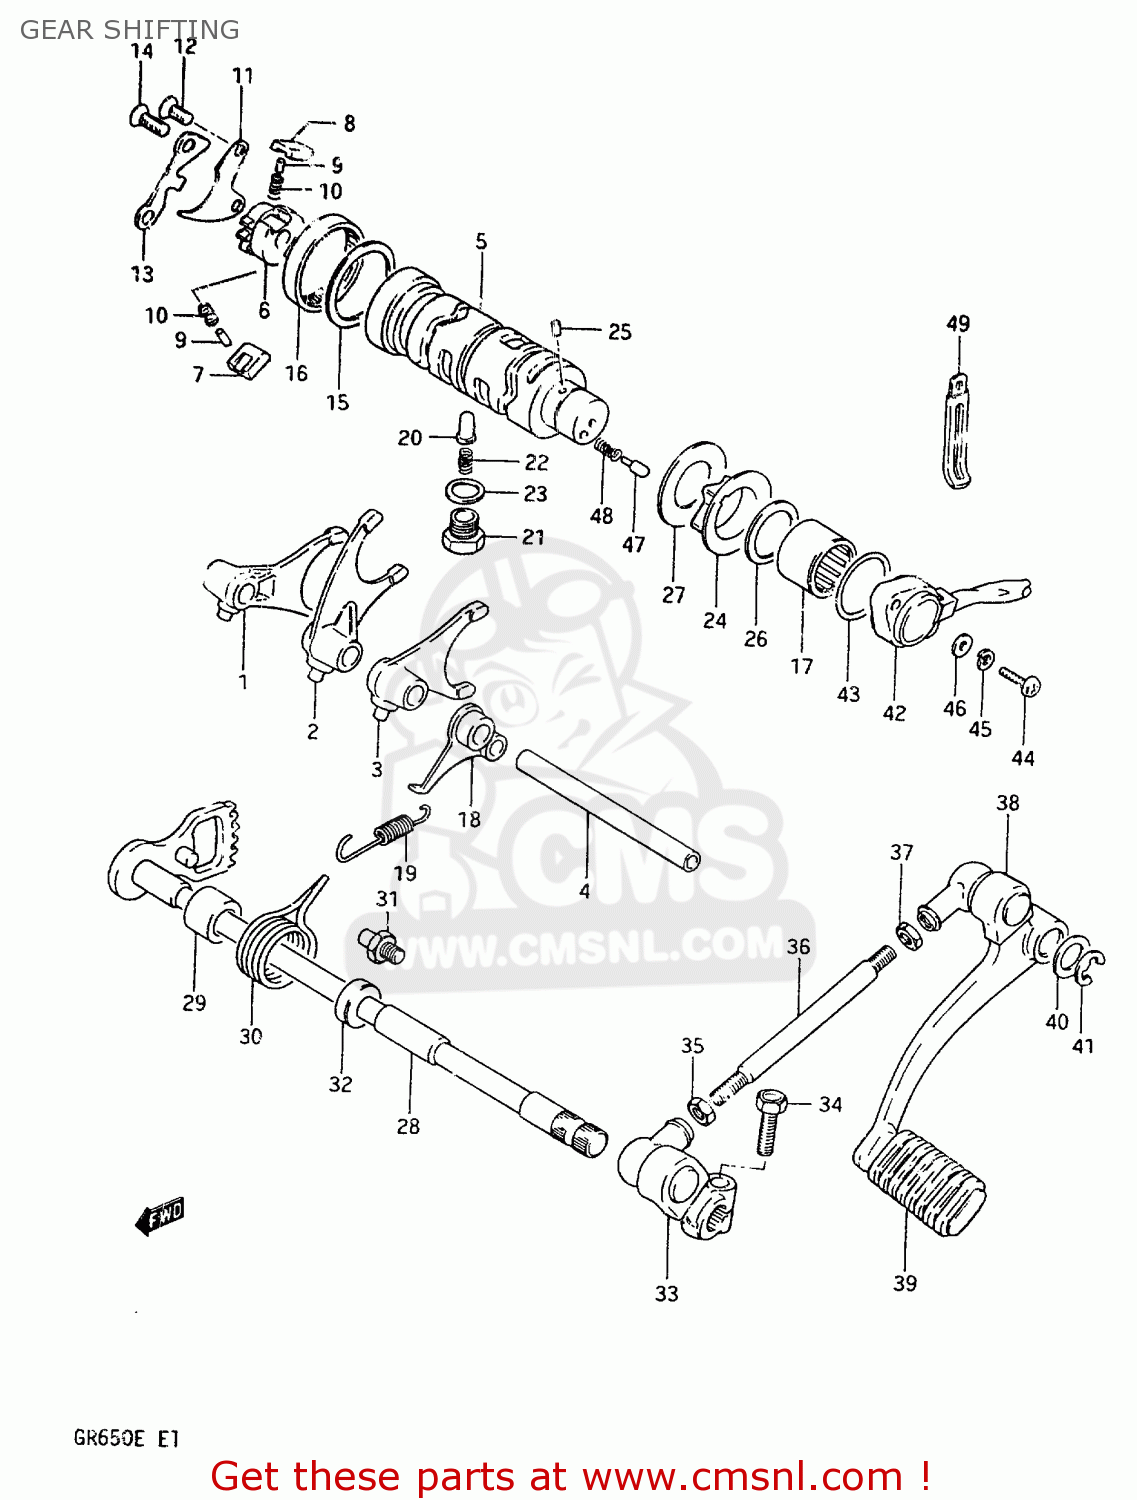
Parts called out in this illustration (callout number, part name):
1	FORK,GEAR SHIFT NO.1
2	FORK,GEAR SHIFT NO.2
3	FORK,GEAR SHIFT NO.3
4	SHAFT,GEAR SHIFT FORK
5	CAM,GEAR SHIFT
6	RETAINER,GEAR SHIFT CAM
7	PAWL,GEAR SHIFT NO.1
8	PAWL,GEAR SHIFT NO.2
9	PIN(5X8)
10	SPRING
11	LIFTER,GEAR SHIFT PAWL
12	SCREW
13	GUIDE,GEAR SHIFT CAM
14	SCREW
15	WASHER (40X49X1)
16	BEARING(43X49X12)
17	BEARING(25X32X12)
18	STOPPER,GEAR SHIFTING
19	SPRING
20	STOPPER,GEAR SHIFTING
21	HOLDER,GEAR SHIFT CAM STOP SPR
22	SPRING
23	GASKET(14X19.2X2) (NAS)
24	PLATE,GEAR SHIFT CAM STOPPER
25	PIN 4X6
26	WASHER
27	WASHER,LOCK
28	SHAFT,GEAR SHIFT
29	SPACER(12X20X15.3)
30	SPRING
31	STOPPER,GEAR SHIFT CAM
32	OIL SEAL
33	ARM,GEAR SHIFT
34	BOLT
35	NUT
36	ROD,GEAR SHIFT LINK
37	NUT
38	LEVER ASSEMBLY,GEAR SHIFTING
39	RUBBER,PEDAL
40	WASHER(12.5X20X1)
41	CIRCLIP
42	BASE ASSEMBLY,NEUTRAL SWITCH TERMINAL
43	O-RING (D:2.4 ID:26.2)
44	SCREW 5X20
45	LOCK WASHER
46	WASHER
47	PIN(5X15.5)
48	SPRING
49	CLAMP
